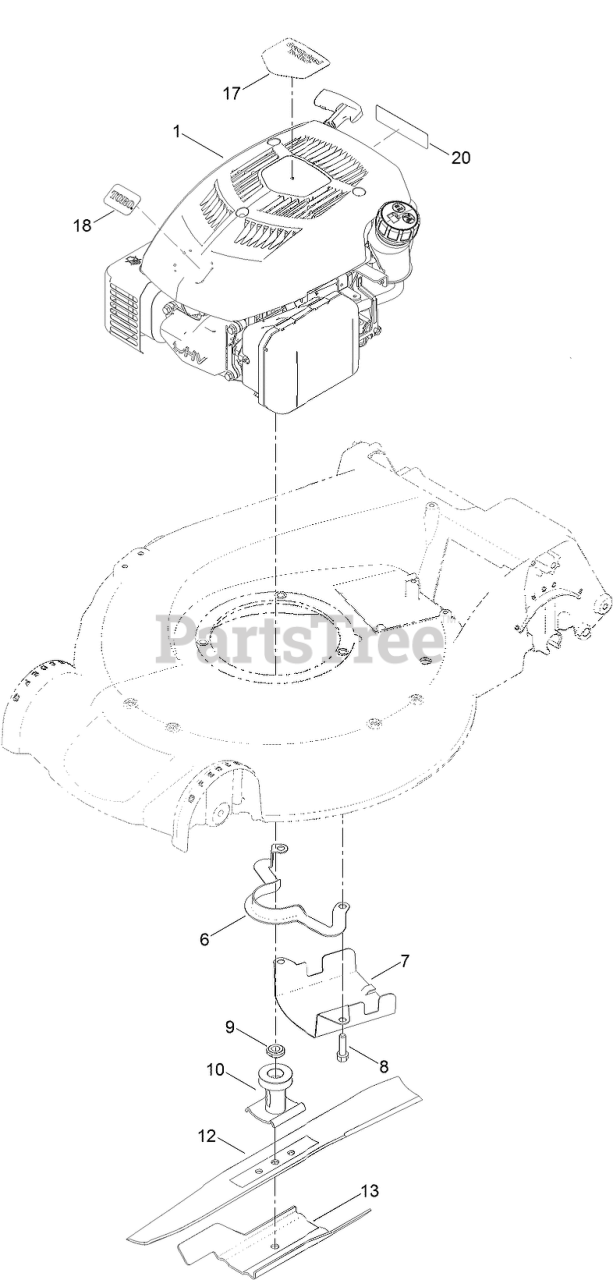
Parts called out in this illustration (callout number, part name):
1	ENGINE-1P65F-2
6	GUIDE-BELT
7	SHIELD-GRASS
8	SCREW-TAPTITE
9	Spacer-Driver
10	DRIVER-BLADE
12	BLADE-RECYCLING
13	Accelerator-Blade
17	DECAL-SHROUD
20	DECAL-ARRESTER, SPARK
